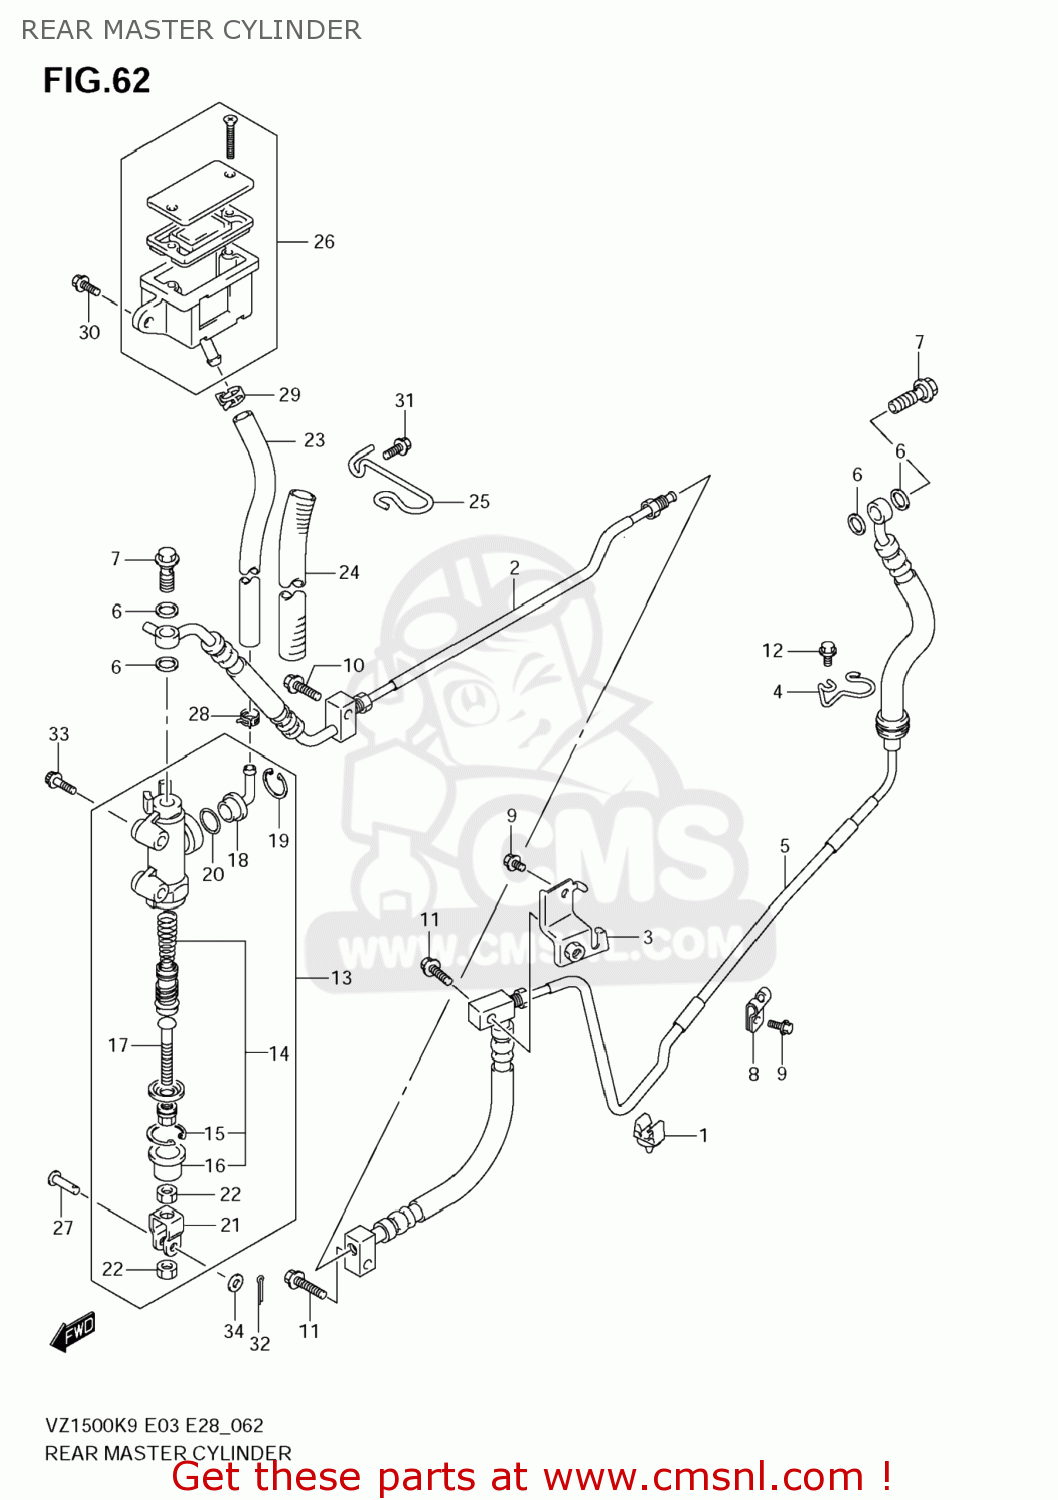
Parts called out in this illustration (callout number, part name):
1	CLAMP,BK PIPE SIDE MEMBER
2	HOSE ASSY,RR BRAKE NO.1
3	CLAMP,RR BRAKE HOSE
4	GUIDE,RR BRAKE HOSE
5	HOSE ASSY,RR BRAKE NO.2
6	WASHER(10X15X1.5)
7	BOLT UNION
8	CLAMP
9	BOLT
10	BOLT
11	BOLT
12	BOLT
13	CYLINDER ASSY,RR MASTER
14	PISTON/CUP SET
15	CIRCLIP
16	BOOT
17	ROD,PUSH
18	CONNECTOR
19	CIRCLIP
20	O RING
21	YOKE
22	NUT
23	HOSE,RR RESERVOIR TANK
24	HEATSHIELD
25	GUIDE,RR RSVR TANK HOSE
26	TANK ASSY,RR RESERVOIR
27	PIN(6X18.2)
28	CLIP
29	CLIP
30	BOLT
31	SCREW
32	PIN
33	BOLT
34	WASHER
